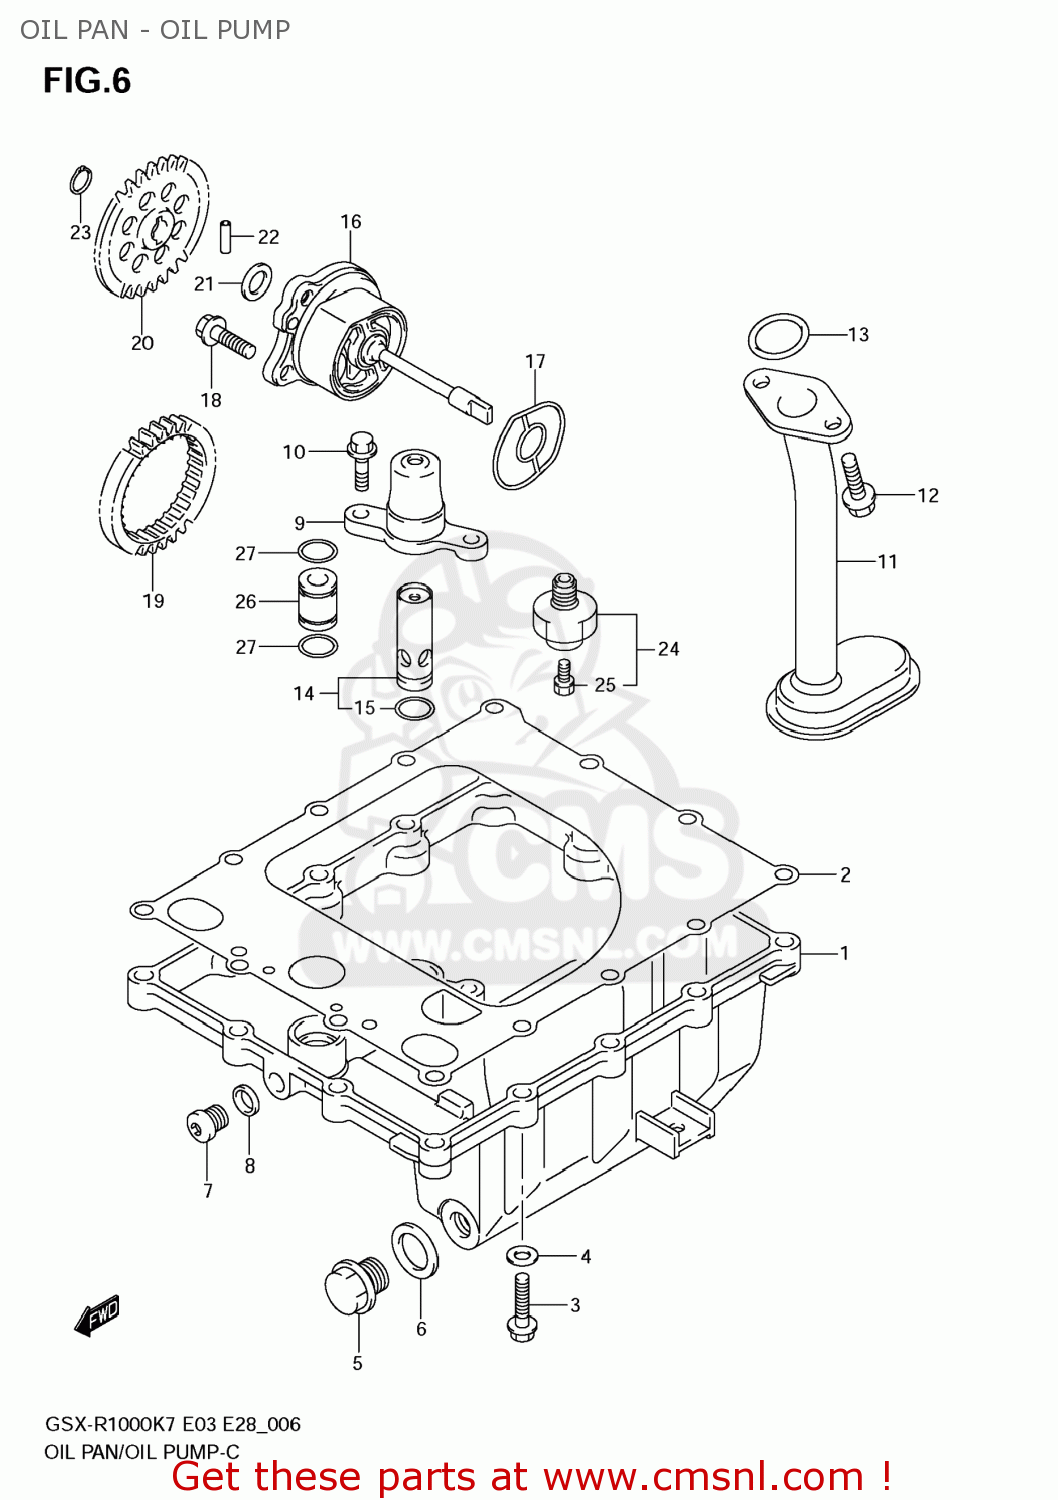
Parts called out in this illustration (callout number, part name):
1	PAN,OIL
2	GASKET,OIL PAN(ASB) (NAS)
3	BOLT
4	GASKET(5.8X13X1.2) (NAS)
5	PLUG(14X20)
6	GASKET(13.8X18.8X4.8) (NAS)
7	PLUG(10X10)
8	GASKET(10X14X3.6) (NAS)
9	CAP,OIL RELIEF VALVE
10	BOLT
11	STRAINER ASSY,ENGINE OIL
12	BOLT(6X16)
13	O RING(D:2.62,ID:20.3)
14	VALVE ASSY,OIL RELIEF(7K)
15	O RING(D:1.9,ID:13)
16	PUMP ASSY,ENGINE OIL
17	O RING,OIL PUMP
18	BOLT
19	GEAR,OIL PUMP DRIVE
20	GEAR,OIL PUMP DRIVEN
21	SHIM(10X18X0.5)
22	PIN(4X15.8)
23	CIRCLIP,10MM
24	SWITCH ASSY,OIL PRESSURE
25	BOLT,OIL PRESSURE SWITCH
26	PIPE,OIL GALLERY
27	O RING(D:1.9,ID:13)
